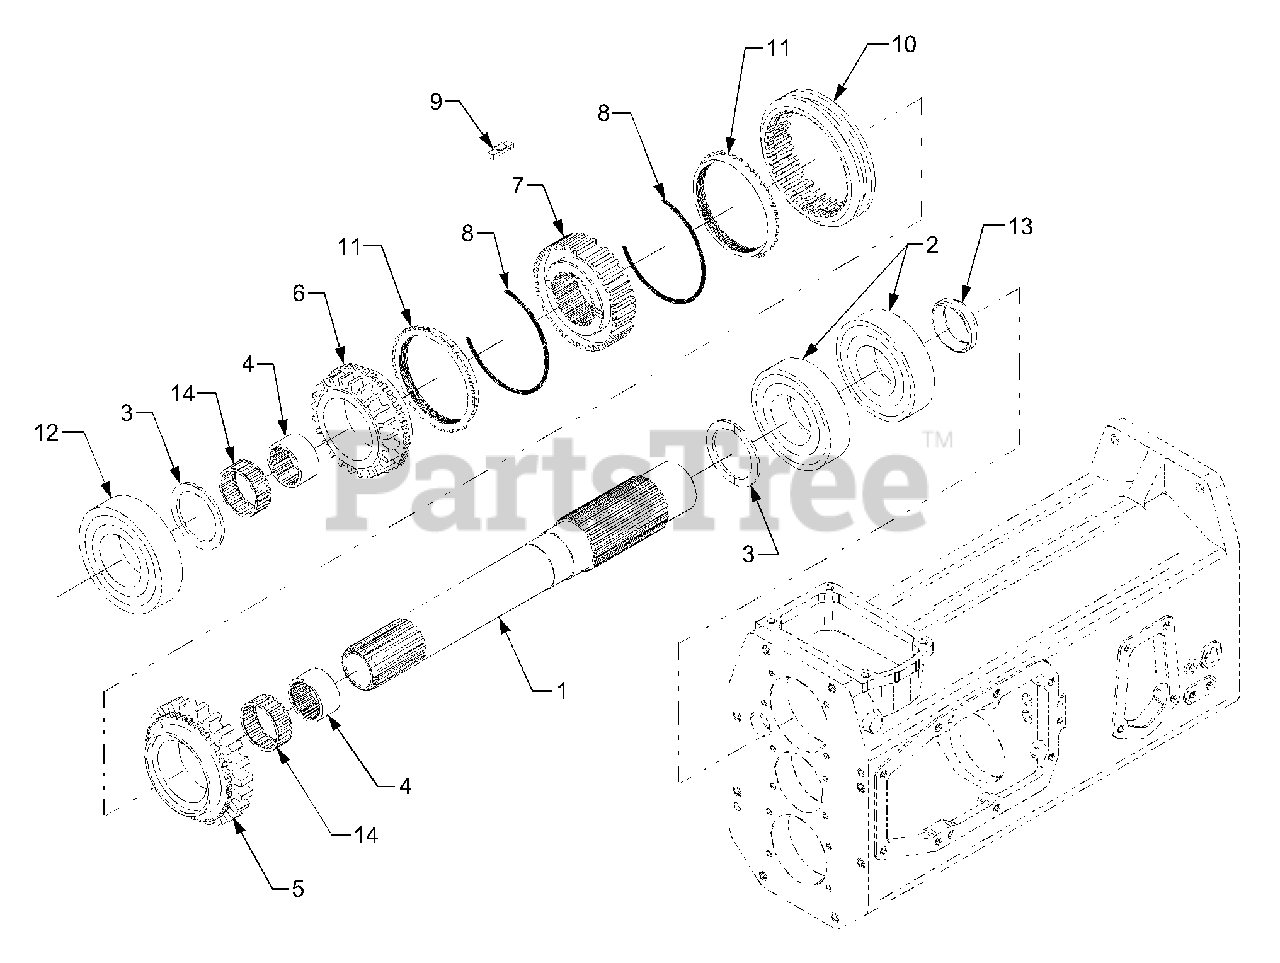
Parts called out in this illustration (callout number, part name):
1	Shaft, Shuttle
2	Bearing, Ball
3	Collar, Thrust
6	Gear, 24
7	Hub, Synchronizer
8	Spring, Synchronizer
9	Key, Synchronizer
10	Shifter
11	Ring, Synchronizer
12	Bearing, Ball
14	Bearing, Needle
